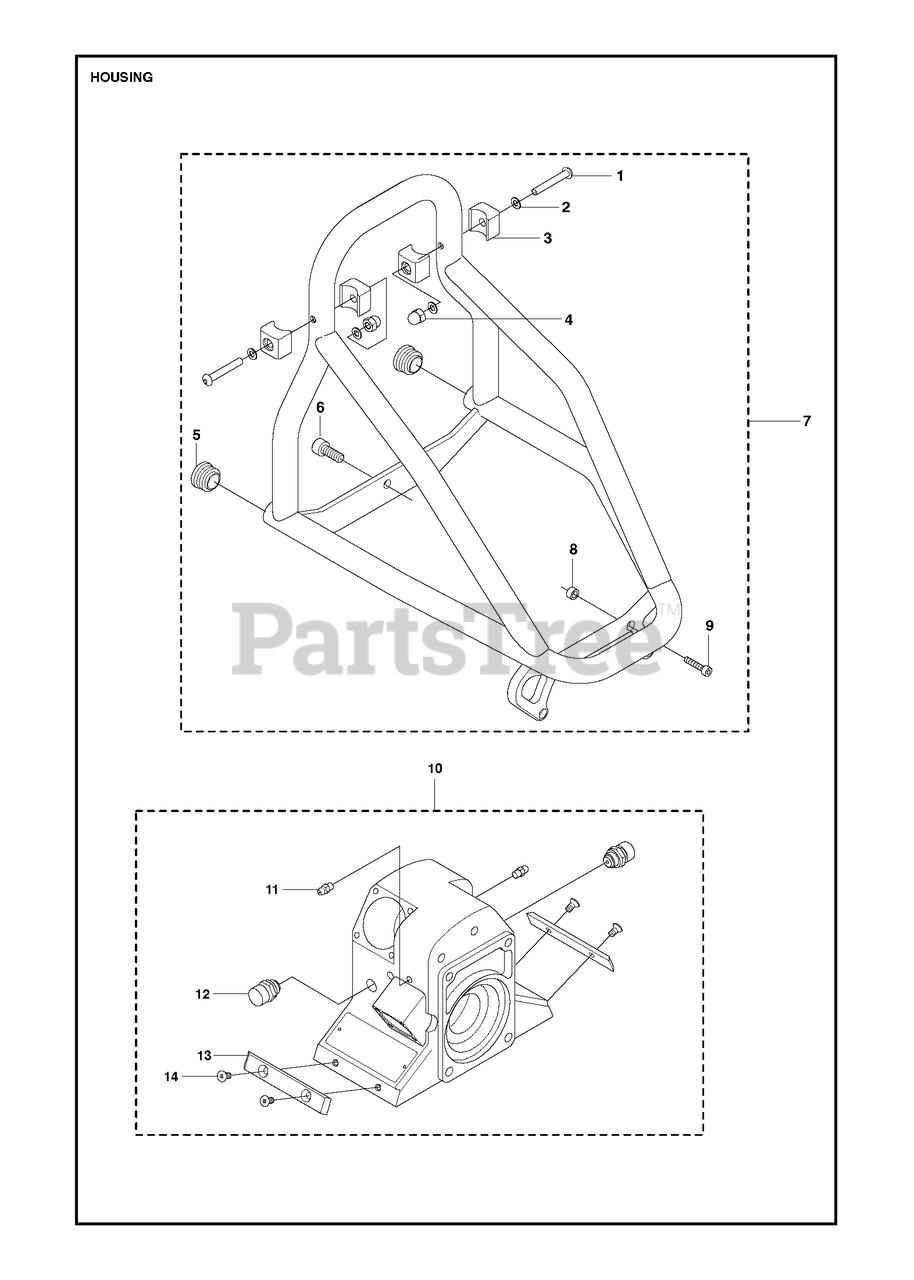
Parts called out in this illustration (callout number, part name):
7	HANDLEBAR ASSYIncl. 1 - 6 , 8 - 9
9	SCREW IHSCM
10	HOUSING ASSYIncl. 11 - 14
